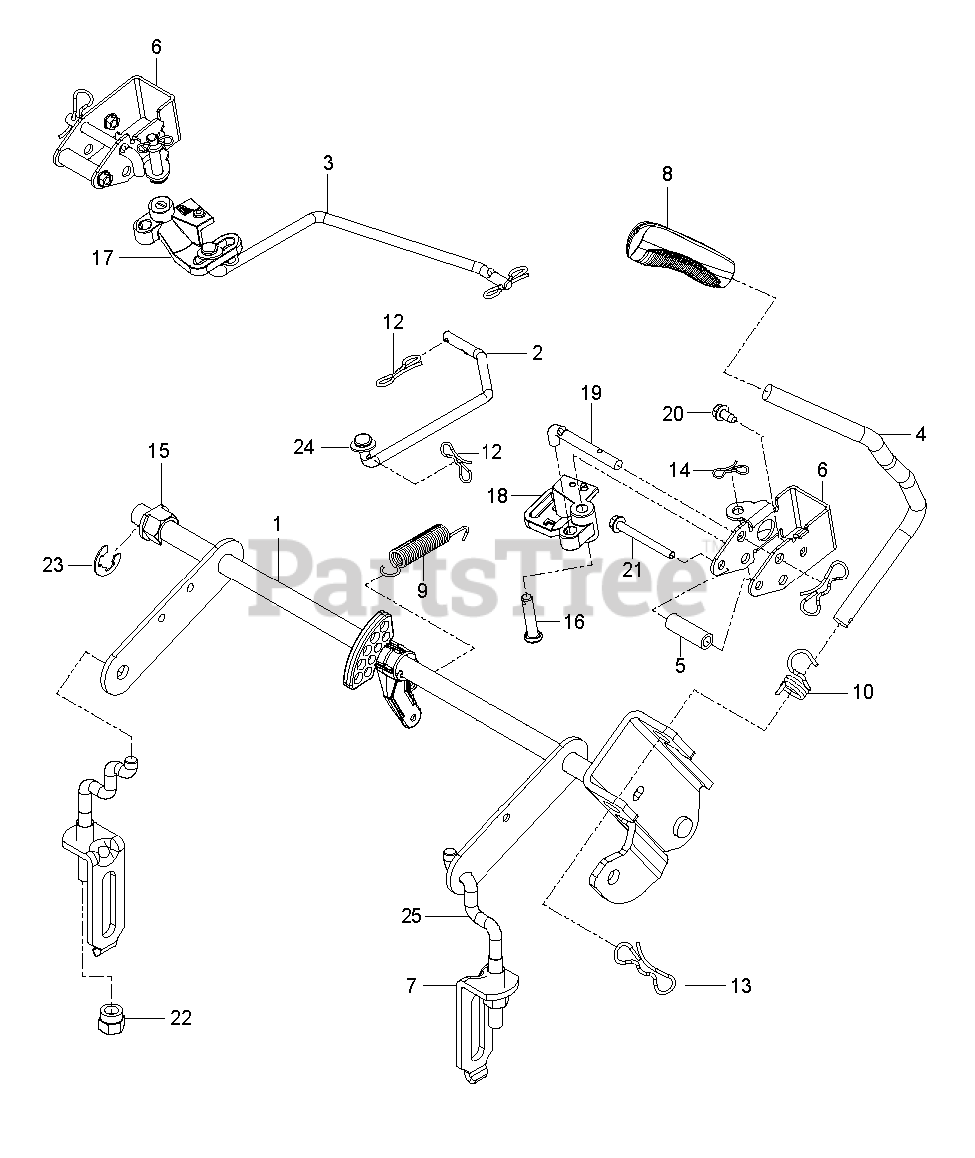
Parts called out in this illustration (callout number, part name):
1	SHAFT ASSY DECK LIFT WELDMENT
2	LINK.BRAKE.PARK.UPPER.LH
3	LINK.BRAKE.PARK.UPPER.RH
6	BRACKET.BELLCRANK.PBRAKE X431
8	GRIP.HANDLE.LIFT.PVC.BLACK
9	RETURN.BRAKE.PARK.AUTO
10	SPRING.TORSION.LIFT.HANDLE
12	PIN COTTER;LOCKING;BOWTIE;1IN
13	PIN.COTTER.7/16.BOW TI.
14	PIN.COTTER.5/16.BOW TI
15	PLASTIC NUT
16	PIN.5.16X1.5
17	BELLCRANK.RH
18	BELLCRANK.LH
19	SCREW THD;ROLL;1/4-20 X 2.25
20	SCREW.1/4-20X5/8
21	SCREW THD;ROLL;1/4-20 X 2.25
22	NUT.LIFT LNK.7/16-2
23	RETAINING RING LT
24	WASHER PLAIN WASHER 3/8 X 0.08
